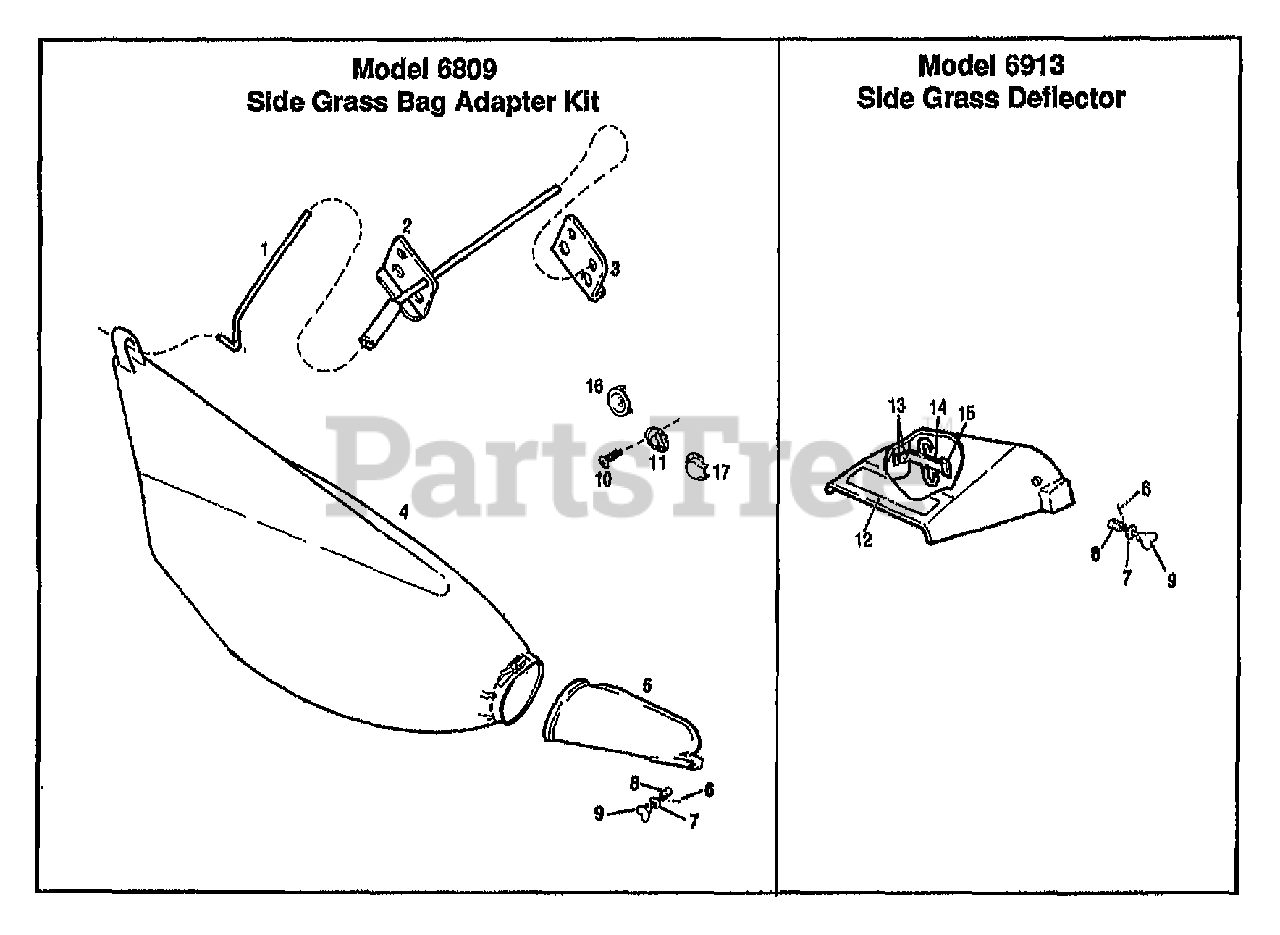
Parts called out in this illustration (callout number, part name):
1	HANGER-BAG {6809}
2	ASSM-BAG SUPPORT {6809}
3	BRKT-BAG HANGER ZP {6809}
4	BAG-GRASS MULCHER {6809}
5	ASSM-CHUTE {6809}
6	PIN-ROLL .093 DIAX.62
7	WASHER-.75X.312X.065 ZP
8	SPRING-COMPRESSION
9	PIN-CHUTE LOCK
10	SCR-EXHAUST DEFLECTOR {6913}
11	DEFLECTOR-EXHAUST {6809} (FOR BRIGGS)
12	DECAL-DANGER {6913}
13	RIVET-POP 3/16"DIA {6913}
14	BRKT-SIDE DISCHARGE {6913}
15	GRIP-VACUCUT {6913}
16	DEFLECTOR-EXHAUST {6809} (FOR TECUMSEH)
17	DEFLECTOR-EXHAUST {6809} (FOR BRIGGS)
